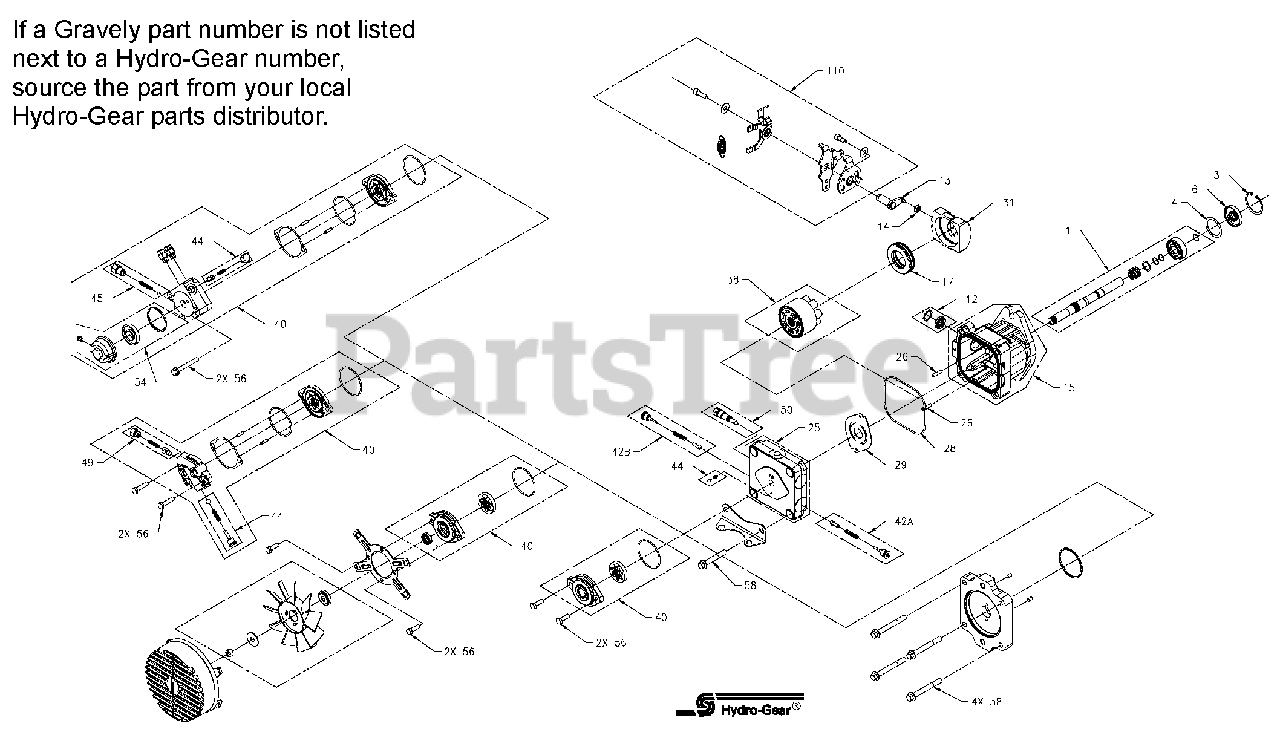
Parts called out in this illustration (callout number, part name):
1	Kit, Input Shaft
3	Ring, Retaining
4	Washer, 1.45 x 1.84 x .04
6	Lip Seal, 17 x 47 x 8
12	Kit, Trunnion Seal
13	Trunnion Arm, Taper Square
14	Slot Guide
15	Kit, Housing
17	Assembly, Thrust Ball Bearing
25	Kit, Endcap
26	Pin
28	O-Ring
29	Valve Plate
31	Variable Swashplate
38	Kit, Cylinder Block
40	Kit, Charge Pump
42	Kit, Shock Valve
44	Kit, Charge Relief
45	Kit, Auxilary Relief Valve
49	Kit, Auxilary Bypass/Check Kit
50	Kit, Bypass Valve
54	Kit, Auxilary Filter Kit
56	Screw, 5/16-18 x 2.5
58	Kit, HSG Bolt
110	Kit, Return
NS	Kit, Overhaul Seal Kit
